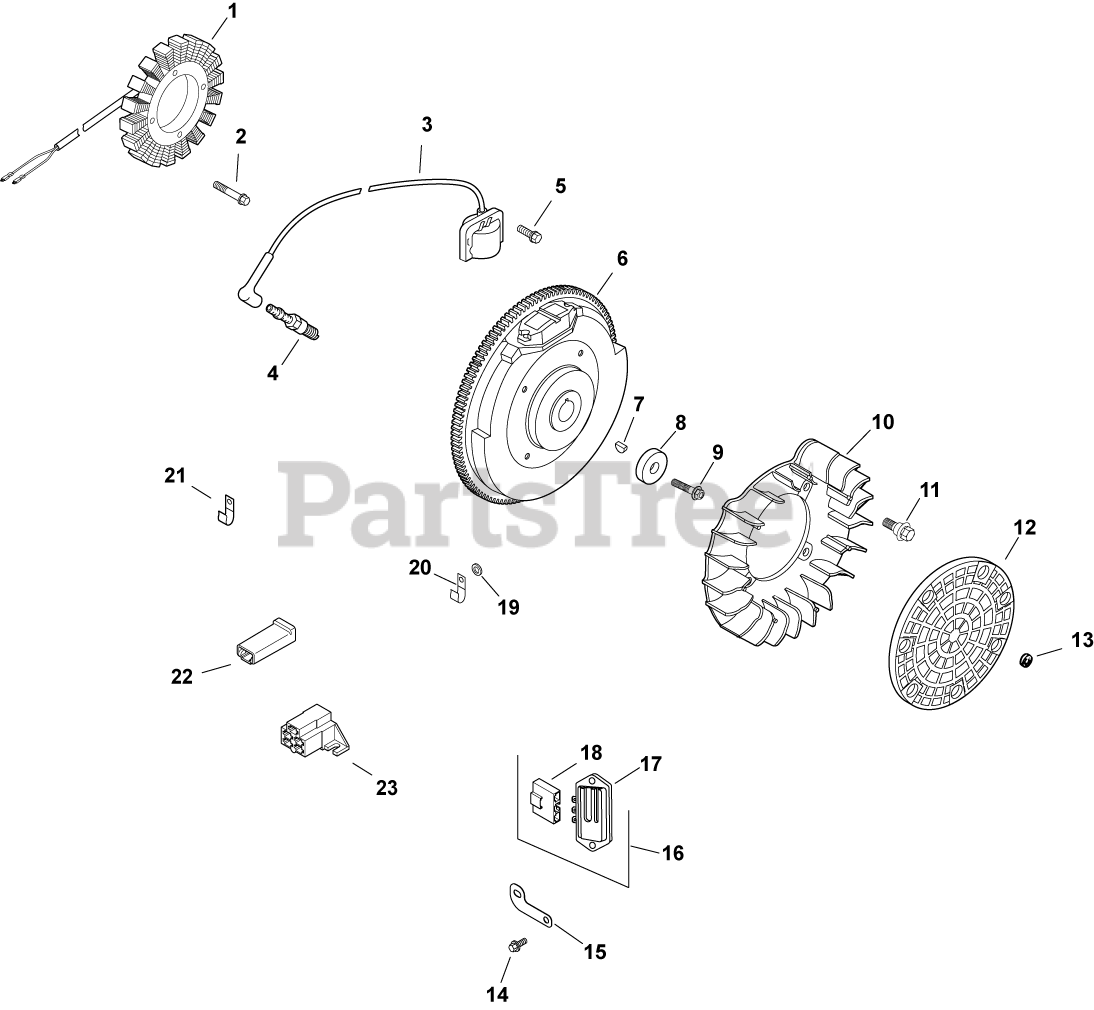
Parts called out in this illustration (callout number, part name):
1	KIT, 25 AMP STATOR ASSY.
2	SCREW, THD FROM M5X0.8X30
3	KIT, MODULE IGNTN (CDI FIXED)
4	PLUG, SPARK (STD)
5	SCREW, FLG THD FRM M5X.8X20-(#25086399S)
7	KEY, 3/16" X 5/8"
8	WASHER, FLAT 13/32"
9	SCREW, FLG M10X1.5X45 - (#25086361S)
10	FAN - USE (#24 157 11-S)
11	BOLT, SHOULDER
12	SCREEN, GRASS
14	SCREW, HEX FLANGE HI-LO
15	BRACKET, GROUND STRAP USE 24 518 12-S
16	KIT, FULL WAVE CONVERSION
17	REG/RECTIFIER (20/25 AMP)-USE 25 403 20-
18	CONNECTOR
19	WASHER, FLAT 1/4" (O.D. 1/2")
21	CLIP, CABLE
22	CONNECTOR (1 CONTACT)
23	CONNECTOR
